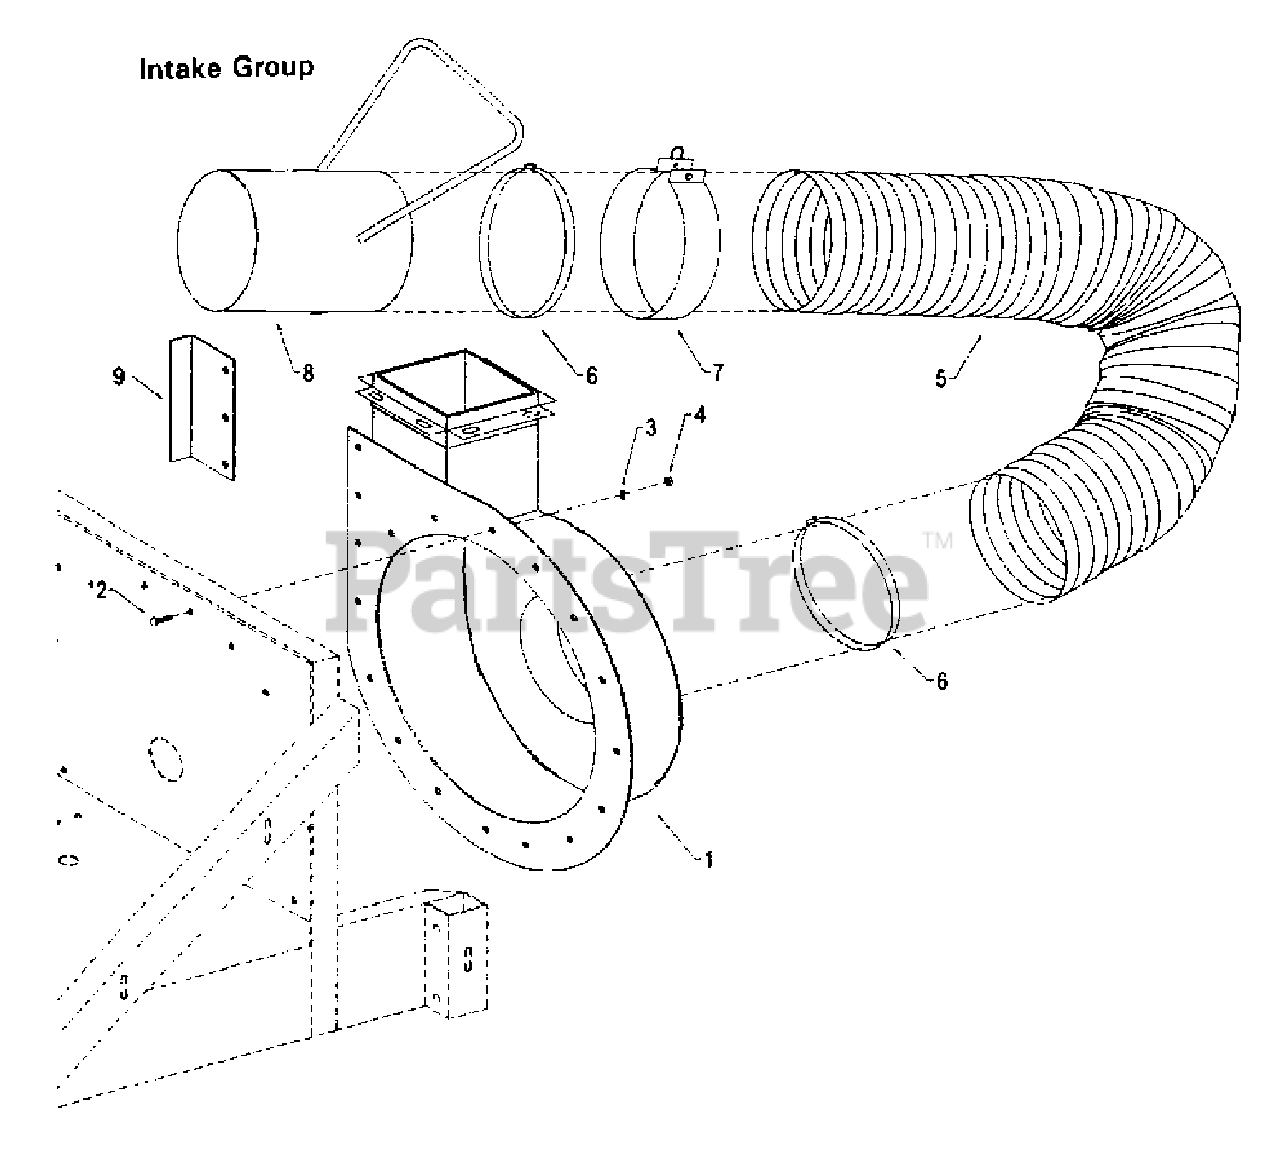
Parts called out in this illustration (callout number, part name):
1	Housing, Impeller - Complete with Liner Kit Below
2	3/8-16 x 1" Hex Bolt
3	3/8 Lock Washer
4	3/8-16 Hex Nut
5	Hose, Intake 12" x 10'
6	Clamp, Hose 12"
7	Band, Hose Support 12" with Hardware
8	Nozzle, Intake 12" w/Adjustable Handle
9	Plate, Hose Protector (CHW Units Only)
